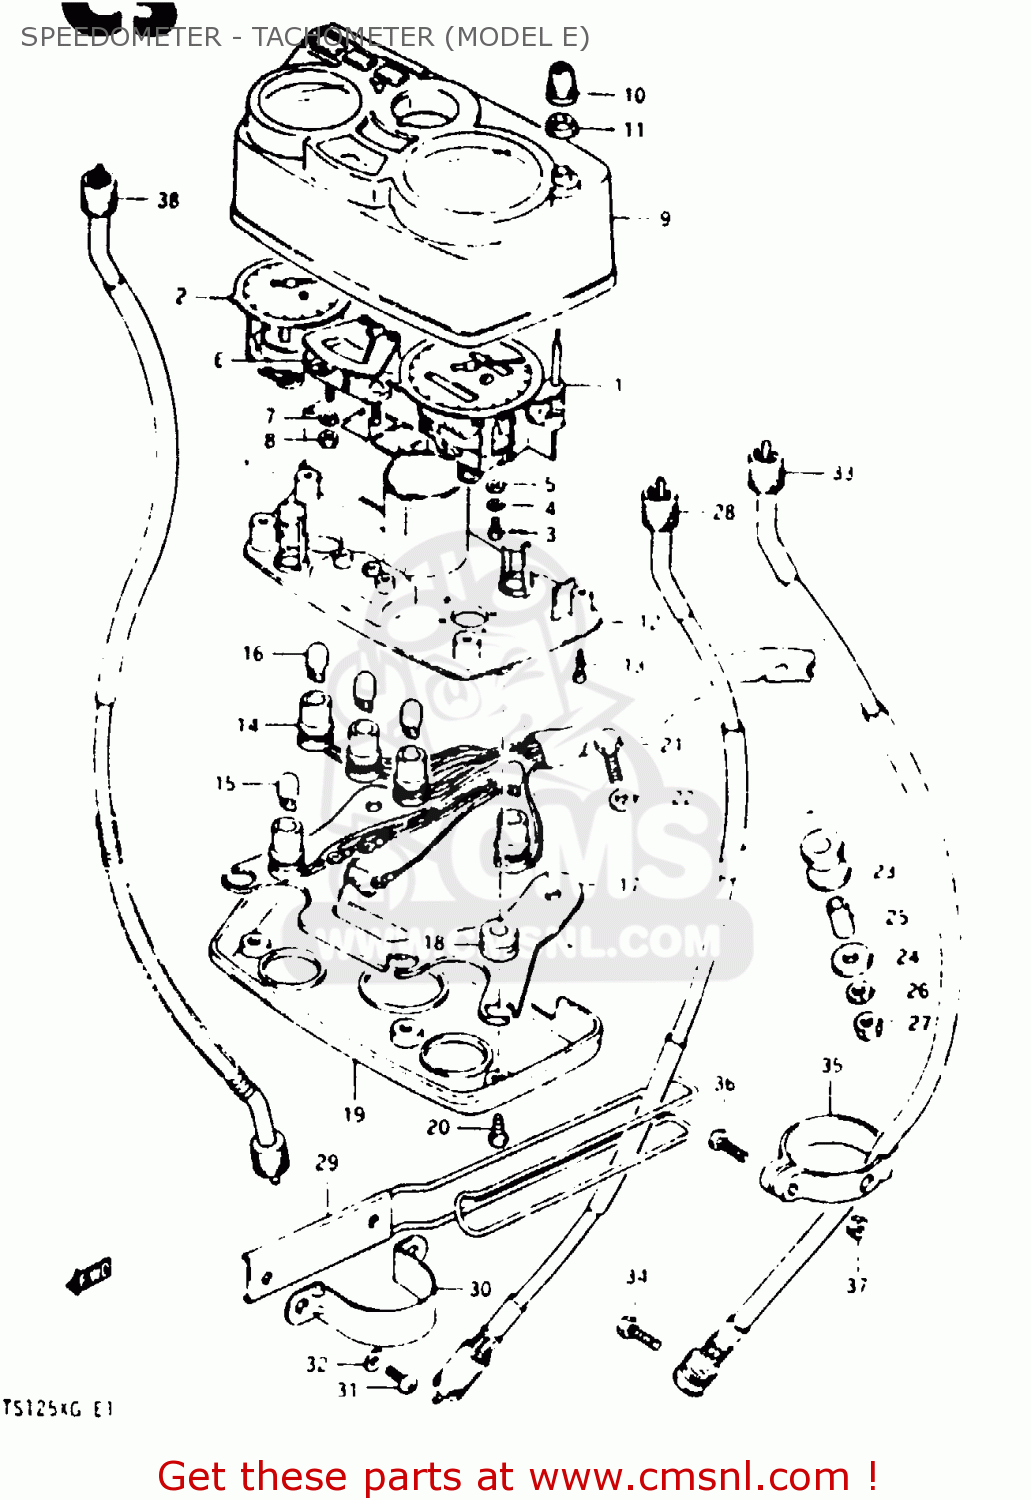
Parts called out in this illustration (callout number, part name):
1	SPEEDOMETER (MILE/KILO)
2	TACHOMETER
3	SCREW
4	LOCK WASHER
5	WASHER 3.3X8X0
6	GAUGE, WATER TEMPERATURE
7	LOCK WASHER
8	NUT
9	HOOD, METER
10	KNOB,TRIP METER
11	SEAL,TRIP KNOB
12	CASE,METER
13	SCREW
14	SOCKET, METER
15	BULB(12V3.4W,T10,BF175-01450A)
16	BULB(12V1.7W,T10,WB121)
17	BRACKET,METER
18	CUSHION
19	COVER, LOWER
20	SCREW
21	BOLT
22	CUSHION
23	CUSHION
24	WASHER (6.5X18X1.6)
25	SPACER (6.1X8X15.5)
26	LOCK WASHER
27	NUT
28	CABLE ASSEMBLY,SPEEDOMETER
29	GUIDE,CABLE
30	CLAMP, CABLE GUIDE
31	SCREW 6X12
32	LOCK WASHER
38	CABLE ASSY,TACHOMETER
